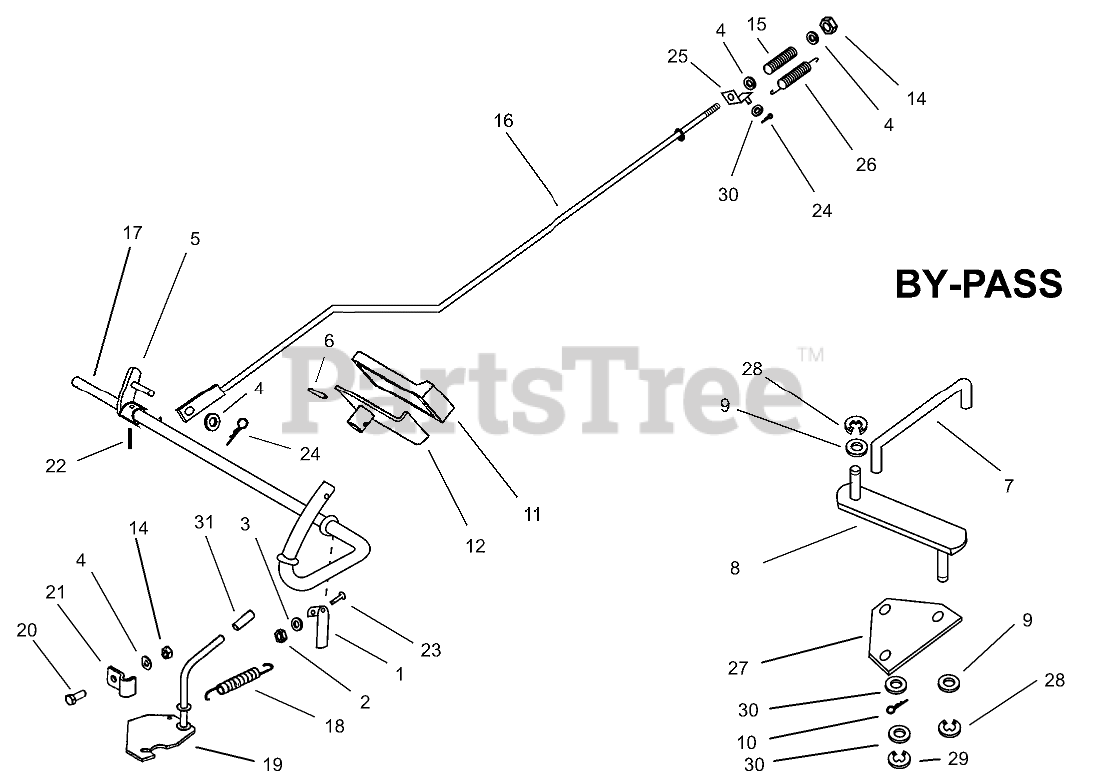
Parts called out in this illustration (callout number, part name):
1	LEVER-SPRING
2	WASHER
3	NUT-HEX
4	WASHER-PLAIN
5	BRACKET-ROD, BRAKE
6	PIN-SPRING
7	ROD-LEVER, BYPASS
8	ARM-BYPASS LEVER
9	WASHER
10	PIN-COTTER
11	PAD-PEDAL
14	NUT-LOCK, NI
15	SPRING-BRAKE
16	ROD-CONNECTING, BRAKE
17	Shaft-Brake
18	SPRING-BRAKE, HAND
19	LEVER-BRAKE, HAND
20	SCREW-HH
21	CLAMP-LEVER, PARKING BRAKE
22	PIN-SPRING
23	SCREW-HEX
24	PIN-COTTER
25	BRACKET-ROD, BRAKE
26	SPRING
27	PLATE-BY-PASS
28	STIRRUP
29	E-CLIP
30	WASHER-FLAT
